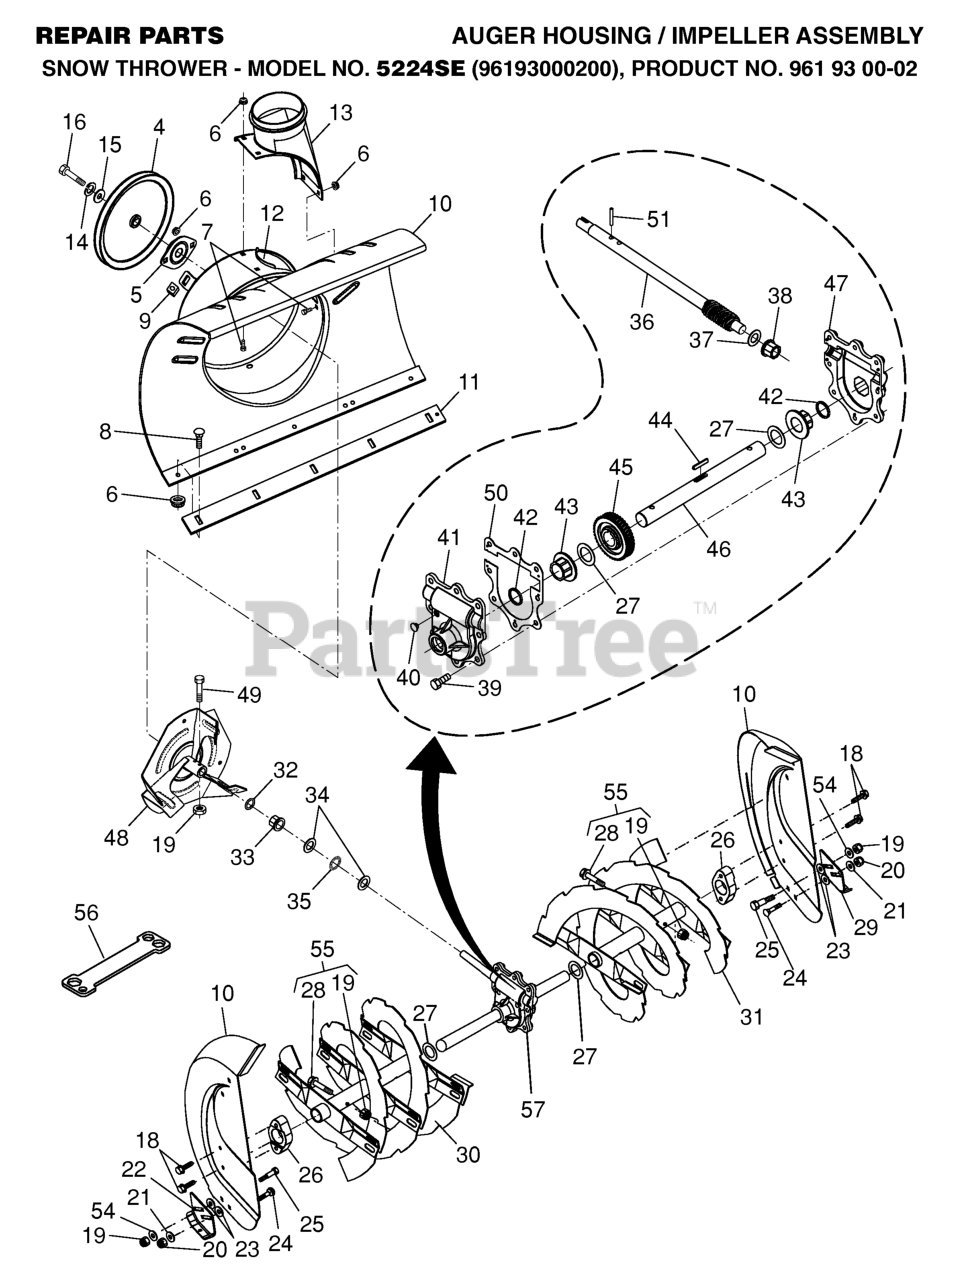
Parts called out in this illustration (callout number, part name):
4	PULLEY, IMPELLER
5	BEARING FLANGE
6	NUT.FLANGE.5/16
7	BOLT.CARRIAGE.5/16-18X
8	BOLT
9	NUT, CAGE 3/8-16
10	RP HOUSING, AUGER 24"
11	BAR, SCRAPER 24"
12	BRACKET, CORNER DISCHARGE
13	BASE DISCHARGE CHUTE
14	WASHER, FLAT
15	WASHER.LOCK.HVY.HLCL.SPR.5/16
16	Screw, Hex Head 5/16-18 x 3/4
18	SCREW, HEX HD 5/16X1
19	LOCKNUT.NYLOC.1/4-20
20	NUT.71038.31-18.HEX.NYLOCK
21	WASHER.20X8.5
22	SKID PLATE RH
23	WASHER, NYLON FRICTION
24	BOLT
25	SHOULDER BOLT
26	BEARING, AUGER
27	WASHER TRUST 1"
28	BOLT.SHOULDER.SHEAR.1/4-20.
29	SKID PLATE LH
30	AUGER.WLDMNT.RH.24.PNT.STD
31	AUGER.WLDMNT.LH.24.PNT.STD
33	BUSHING FLANGE 3/4
34	WASHER, THRUST 3/4
35	BEARING TRUST 3/4 NTA-1220
36	SHAFT, IMPELLER
37	WASHER, THRUST 5/8
38	BUSHING.FLANGE.(.625X.75)
39	SELF-TAPPING SCREW 5/16-18X3/4
40	PLUG.AUGER.GEAR.BOX.SNOW
41	HOUSING.GEARBOX.RH.SNOW
43	BUSHING FLANGE 1"
44	KEY, SQUARE 1/4 X .875
45	WORM GEAR
46	SHAFT, AUGER
47	LH GEARBOX HOUSING
48	IMPELLER ASSY
49	SCREW.HEX.HD1/4-20X
50	GASKET.AUGER.GEARBOX
51	PIN, ROLL 3/16 X 1-1/8
54	WASHER
55	KIT, BOLT, SHEAR
56	RP WRENCH, SNOWTHROWER
57	GEARBOX ASSY.
